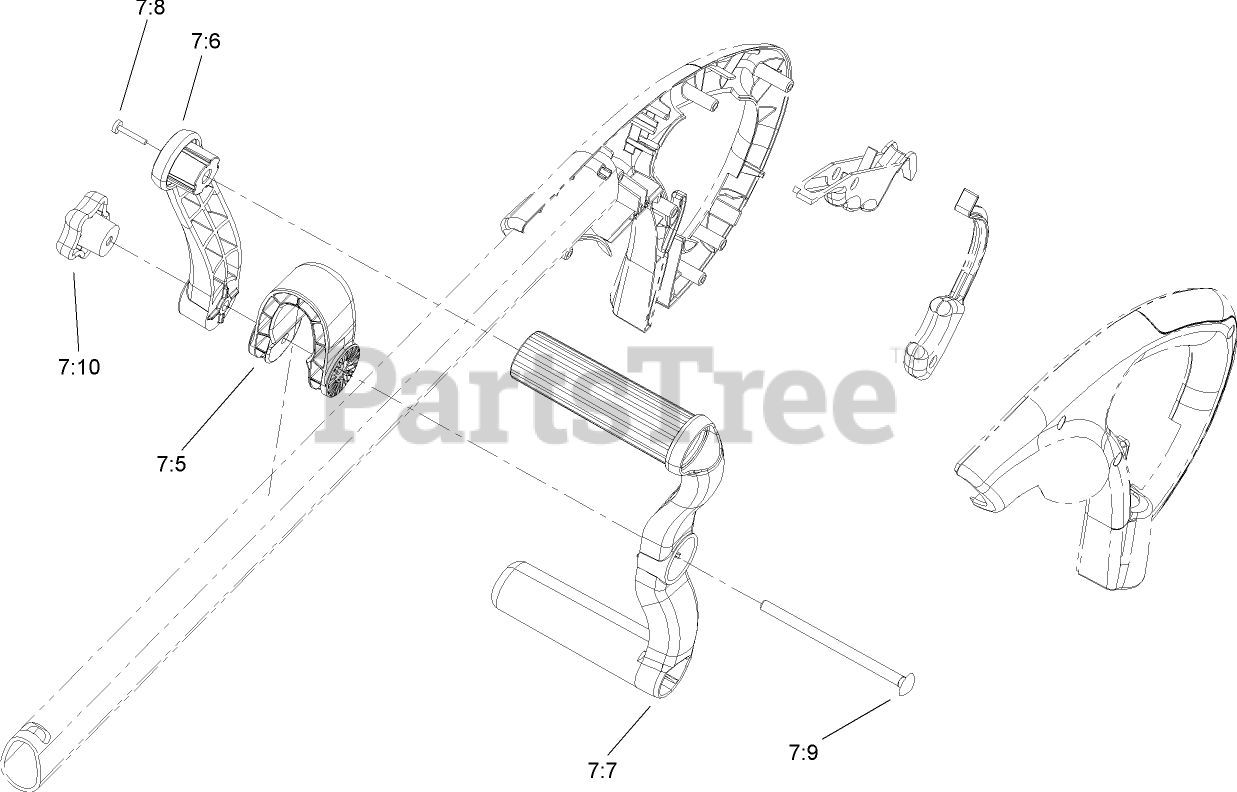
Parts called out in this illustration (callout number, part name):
7	ASSIST HANDLE ASM
7:5	COLLAR-HANDLE, ASSIST
7:6	HANDLE-ASSIST, RIGHT
7:7	HANDLE-ASSIST, LEFT
7:8	SCREW-PPH
7:9	SCREW-CARRIAGE
7:10	KNOB-HANDLE
